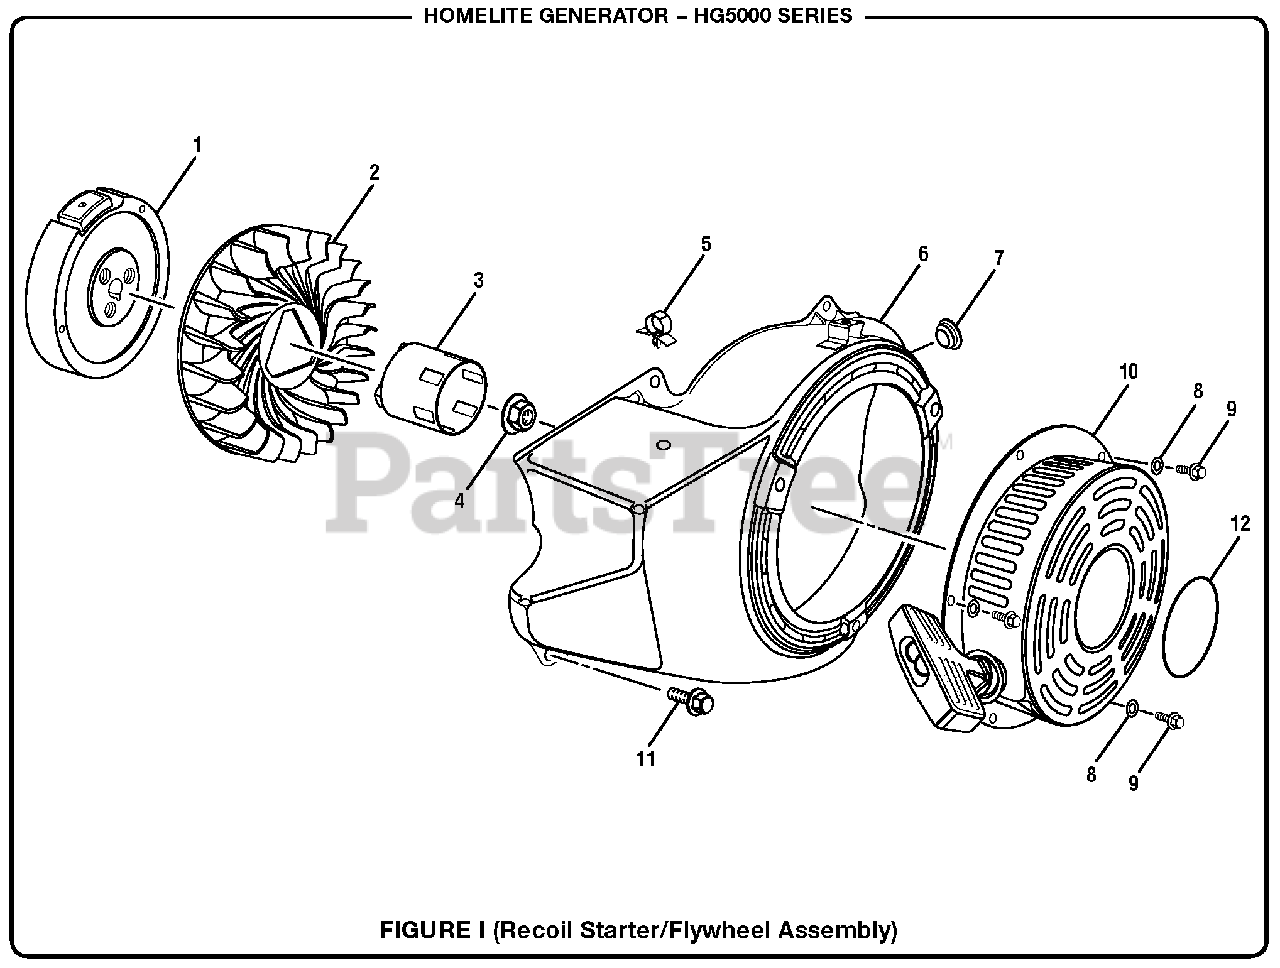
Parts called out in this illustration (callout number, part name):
2	Flywheel Fan
3	Starter Cup
4	Nut (M14 x 1.5 mm)
5	O-Ring (Fan Case)
6	Fan Case Assembly
7	Grommet (Fan Case)
8	Washer (M6)
9	Bolt (M6 x 8 mm, Flange Hd.)
10	Recoil Starter Assembly
11	Bolt (M6 x 12 mm, Flange Hd.)
12	Engine Recoil Label
